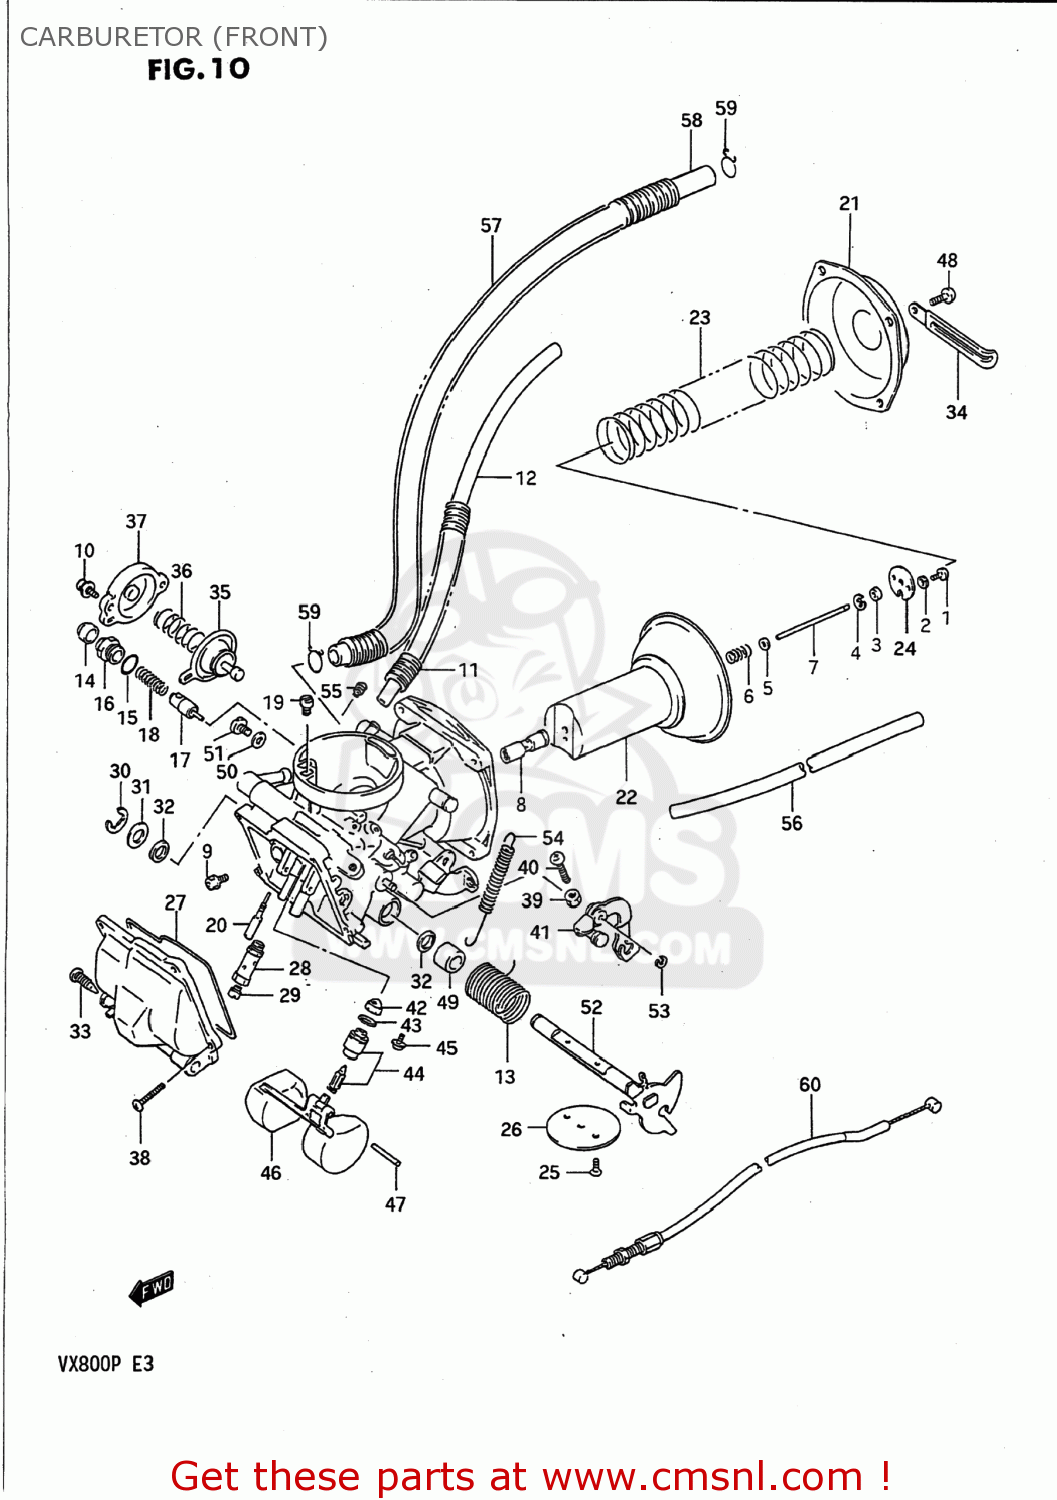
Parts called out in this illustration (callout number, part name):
1	SCREW
2	LOCK WASHER
3	RING
4	CLIP
5	WASHER
6	SPRING
7	NEEDLE,JET
8	JET,NEEDLE(P-2)
9	SCREW
10	SCREW
11	HOSE
12	HOSE
13	SPRING,SHAFT RETURN
14	CAP
15	O RING
16	HOLDER,GUIDE
17	PLUNGER,STARTER
18	SPRING
19	JET,AIR(65)
20	JET
21	COVER
22	DIAPHRAGM,CARBURETOR
23	SPRING,DIAPHRAGM
24	PLATE
25	SCREW
26	VALVE,THROTTLE
27	O RING,FLOAT CHAMBER
28	HOLDER,MAIN JET
29	JET,MAIN(122.5)
30	E RING
31	GASKET,THROTTLE SHAFT (NAS)
32	SEAL,THROTTLE SHAFT
33	PLUG
34	CLIP
35	DIAPHRAGM ASSY
36	SPRING
37	COVER
38	SCREW
39	NUT
40	SCREW
41	LEVER,ASSEMBLY
42	FILTER
43	O-RING,NEEDLE VALVE
44	VALVE ASSY,NEEDLE
45	SCREW
46	FLOAT
47	PIN,FLOAT
48	SCREW 5X12
49	RING
50	GASKET,DRAIN PLUG (NAS)
51	SCREW
52	SHAFT ASSEMBLY,THROTTLE
53	E-RING
54	SPRING
55	JET,AIR(1.2)
56	(CA) HOSE SET,FUEL
57	HOSE
58	HOSE(6.5X11.5X600)
59	CLIP
60	CABLE,IDLE SYNCRO
